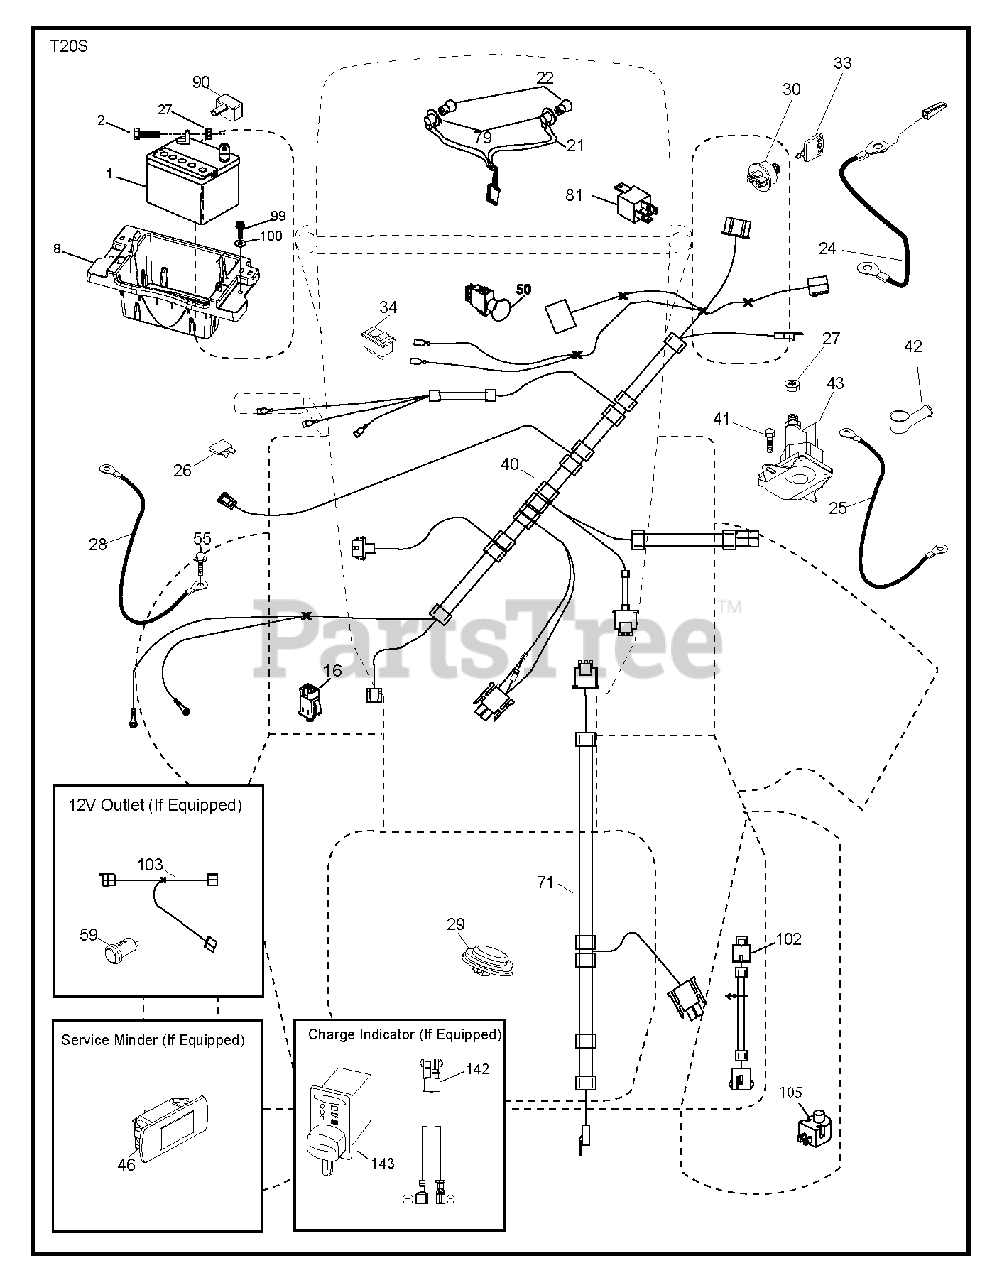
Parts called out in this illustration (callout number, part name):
1	Battery, Dry 30 Amp
2	BOLT.HEX.1/4.X.3/4.DICHROMATE
8	TRAY.BATTERY BOX.FRONT
16	SWITCH INTERLOOK PUSH-IN
21	HARNESS.LIGHT W/4152J BULBS
24	CABLE.FRBATT.W/WIRE.8GA.8
25	CABLE.STARTER.6G.BL/RED.17.5
26	FUSE 20AMP
27	NUT
28	CABLE.GROUND.21"BLK.8GA.90T
29	SWITCH.SEAT.DELTA.OPC.
30	SWITCH.IGN.DELTA.W.LGH.ROS
33	KEY.CHAIN.BLISTER.PACK.GEN.INT
40	HARNESS.IGN.ELEC.RELAY.TEX.46"
41	SCREW
42	TERMINAL COVER
43	SOLENOID.W/BRASS.PLUNGER
46	RP GUAGE.SRVCMNDR.HRMTR.
50	RB PTO.SWITCH.8 TERMINAL.BLACK
55	SCREW 5/16"
71	HARNESS-CHASSIS SUB
79	BULB HOLDER ASM.
81	RELAY HARNESS.SEALED
90	COVER.TERMINAL.BATTERY
99	SCREW HEXWSHR 1/4-20X3/4
102	HARNESS PIGTAIL PCH TEX ROS
105	REVERSE SWITCH
142	CHARGE.PORT
143	CHARGE.PORT.PIGTAIL HARNESS
